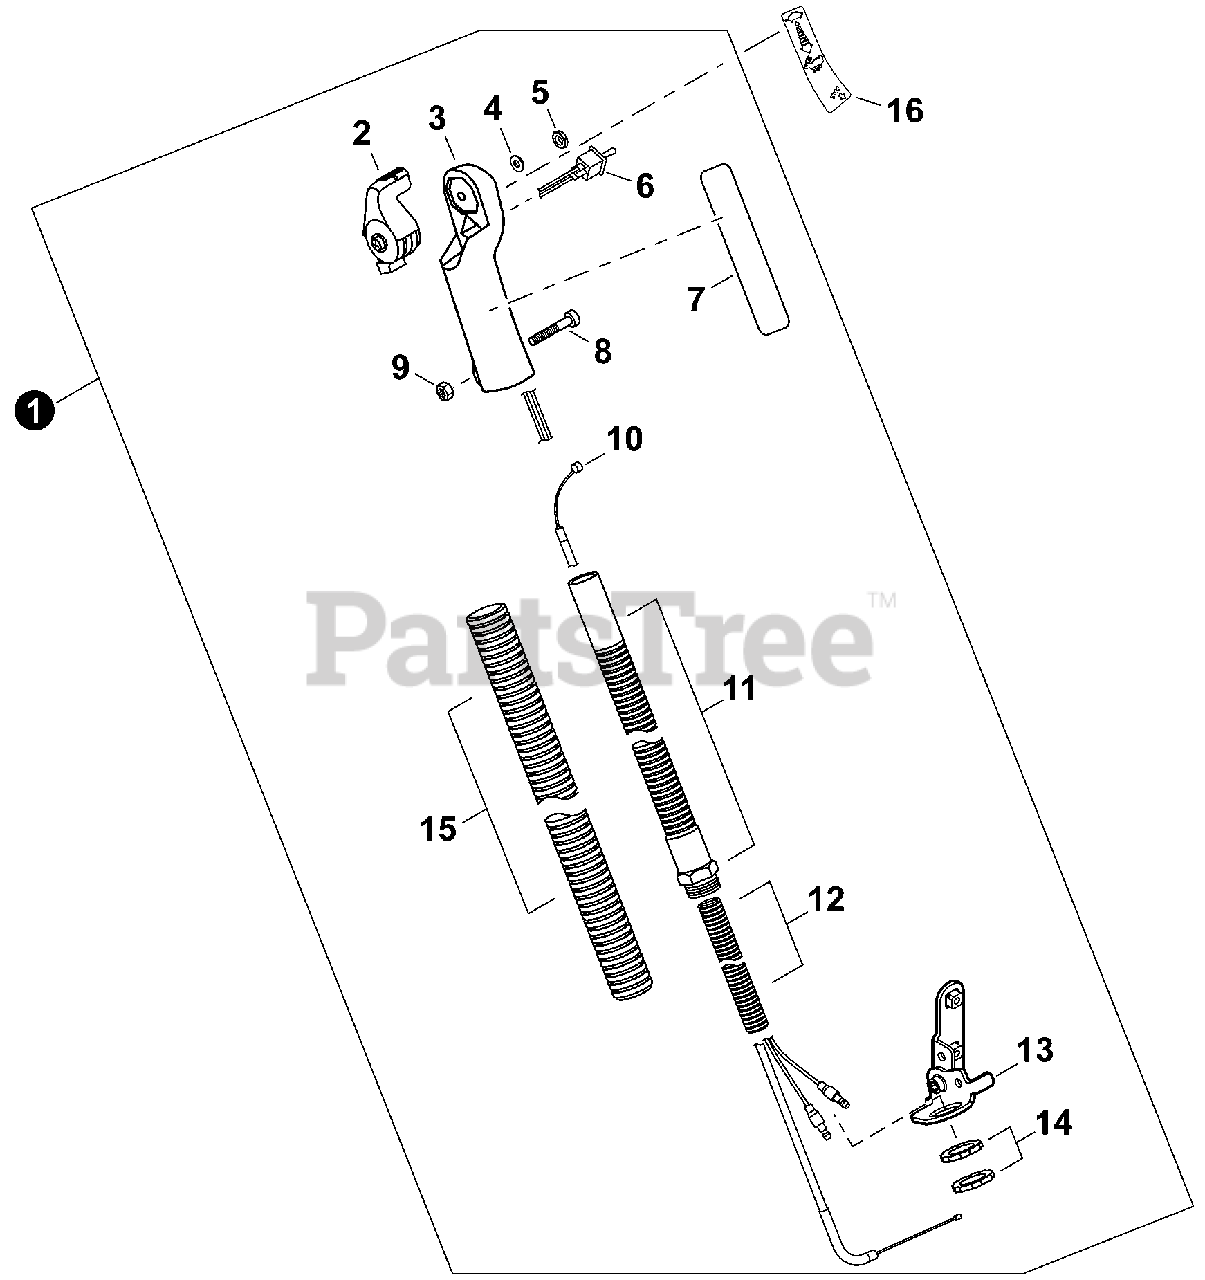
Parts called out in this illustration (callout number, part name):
1	THROTTLE CONTROL ASSY
2	CONTROL, THROTTLE
4	WASHER 5.5×12×0.8
5	U-NUT M5
6	SWITCH, ON-OFF
7	PLATE, GROUND
8	BOLT M5×16
9	NUT M5
10	CABLE, THROTTLE
11	ARM, FLEX
12	TUBE, FLEXIBLE
13	BRACKET, MOUNTING
15	TUBE, OUTER FLEX
16	LABEL, THROTTLE
